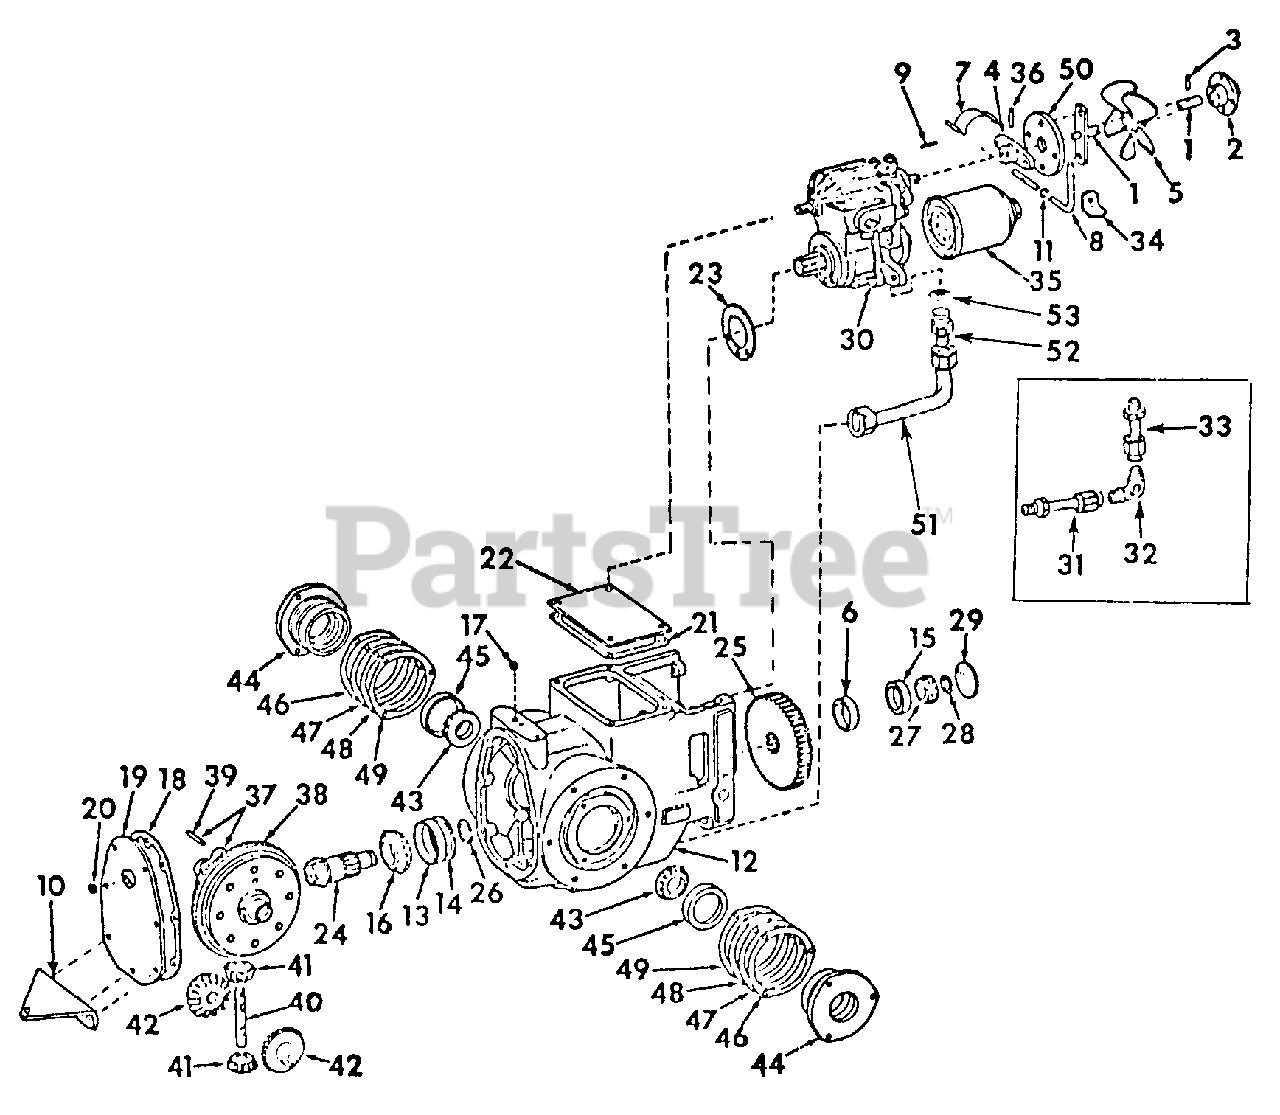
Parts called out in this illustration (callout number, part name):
1	Rod Assy, Drive
2	Hub Assy, Drive Plate
3	Pin, 1/4 X 1-1/2 Dowel
4	Arm, Coupling
5	Fan, Cooling
6	Spacer, Pinion Shaft Gear
7	Lever, Dump Valve
8	Rod, Dump Valve
9	Pin, 1/8 X 3/4 C-Z Hv Coiled Spring
10	Drawbar, Fixed
11	Grommet, Rubber
12	Case Assy, Transmission
13	Bearing, Bevel Pinion Shaft Rear Cup
14	Shim, Rear Bearing Cup, .004
15	Bearing, Bevel Pinion Shaft Front Cup
16	Bearing Assy, Bevel Pinion Shaft Rear Cone
17	Plug, Breather
18	Gasket, Rear Cover Plate
19	Plate Assy, Rear Cover
20	Plug, 1/2-14 Auto Sq Soc Hd Drain
21	Gasket, Top Cover
23	Gasket, Front
24	Shaft, Bevel Pinion
25	Gear, Constant Mesh -66T
26	Ring, Gear Retainer
27	Bearing Assy, Bevel Pinion Shaft Front Cone
28	Ring, Pinion Shaft Front Brg Retainer, .125
29	Plug, 2-1/8 Expansion
30	Transmission Assy, Hydrostatic Drive
31	Not used in this application
32	Not used in this application
33	Not used in this application
34	Bracket, Lever Retaining
35	Filter Assy
36	Pin, 1/4 X 1-1/2 Hv Coiled Spring
37	Case w/Drive Gear, Differential
38	Gear, Drive -46T
39	Pin, Pinion Shaft Lock
40	Shaft, Pinion
41	Pinion, 10T
42	Gear, Side
43	Bearing Assy, Cone
44	Cage Assy, Differential Bearing
45	Bearing, Cup
46	Shim, Brg Retainer, .004
47	Shim, Brg Retainer, .007
48	Shim, Brg Retainer, .0149
49	Shim, Brg Retainer, .0299
50	Disc, Flexible Coupling
51	Tube Assy, Transmission
52	Union, 7/8-14 37 Deg Hyd Flared Tube Short Swivel
53	O-Ring, 3/4 X 15/16 X 3/32
